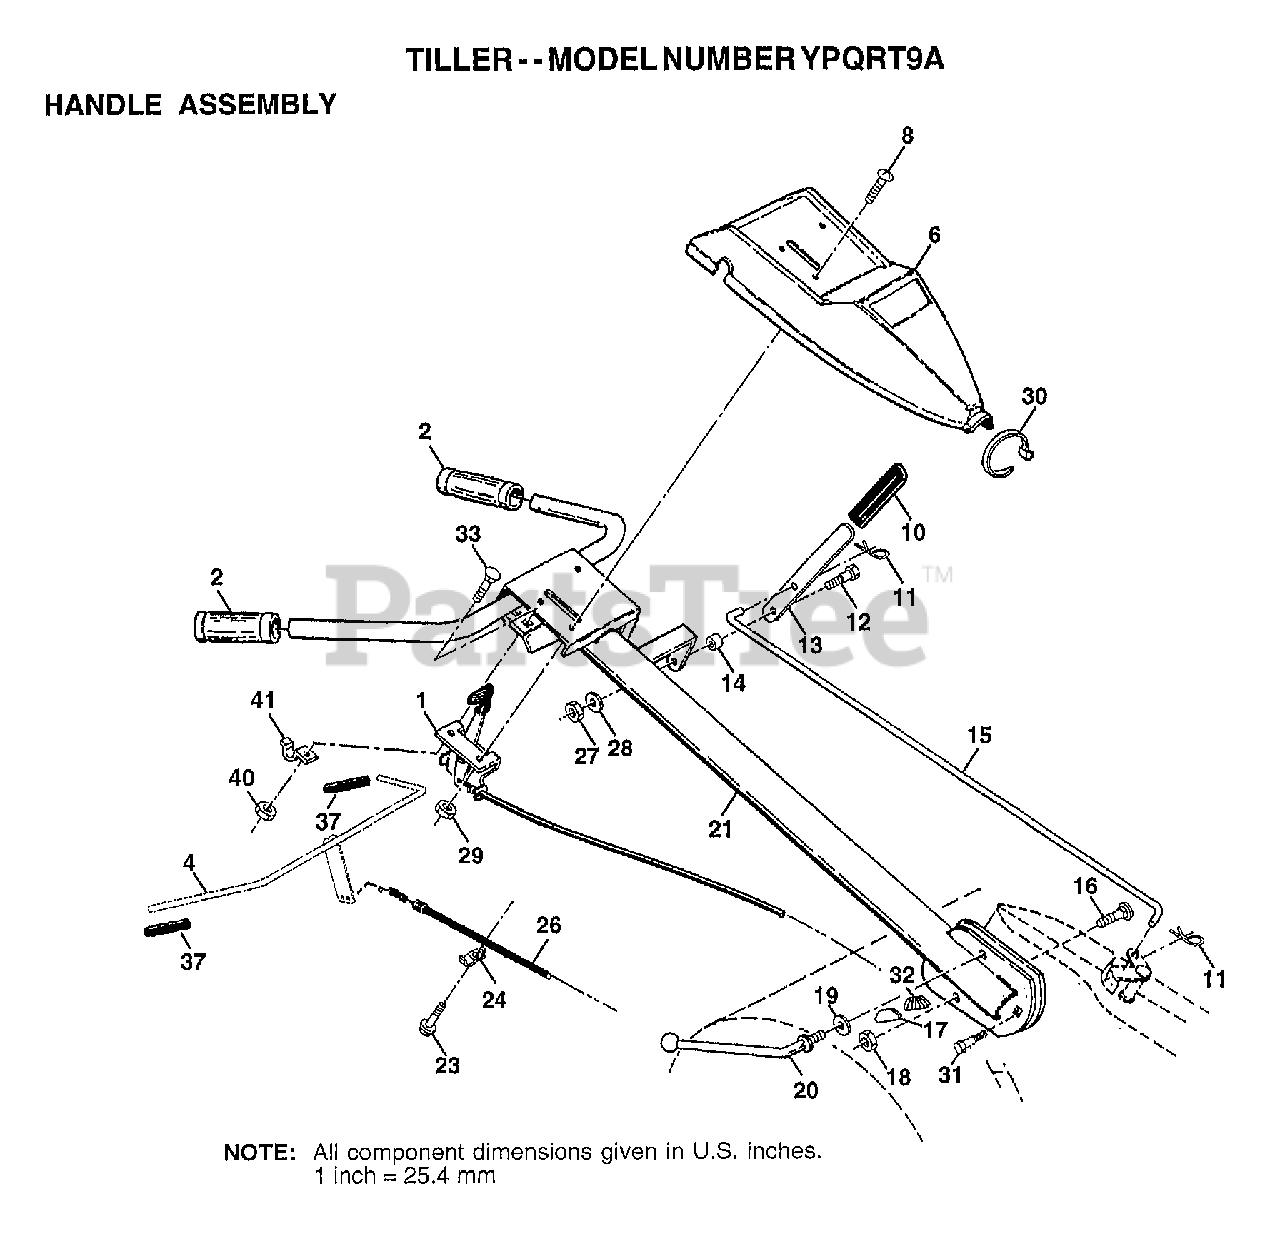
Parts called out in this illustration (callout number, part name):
1	CONTROL.THROTTLE
4	BAR ASM CONTROL
6	"PANEL,CONT TI"
8	SCREW.PNHD.10-24
10	GRIP T
11	RETAINER M
12	SHOULDER BOLT ST
13	SHIFT HANDLE CRT
14	GROMMET CRT
15	ROD.SHIFT
16	BOLT D
17	LOCK CRT
18	LOCKNUT
19	WASHER CRT
20	LEVER LOCK CRT
24	CONDIUT CLIP T
26	CABLE.CLUTCH
28	LOCKWASHER
30	TIE CABLE CRT
31	BOLT PIVOT
32	LOCK.HANDLE
33	BOLT
37	GRIP BAR CRT
40	NUT
